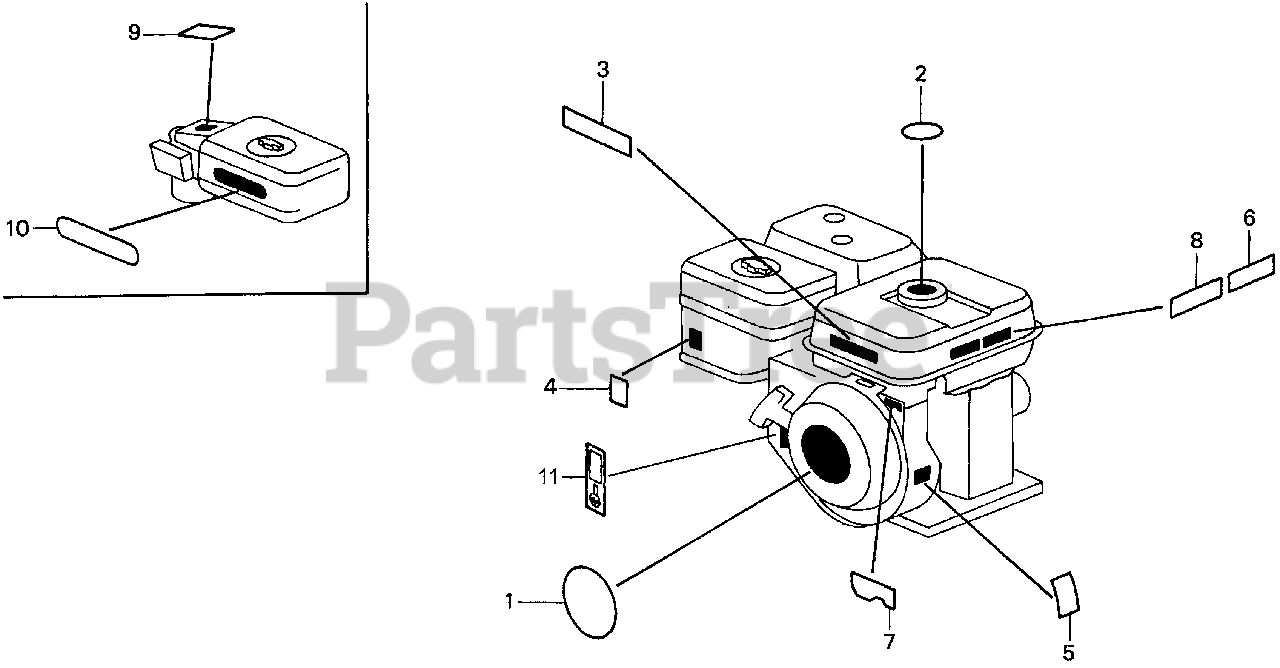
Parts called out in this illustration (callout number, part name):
1	EMBLEM (INTERNAL)
1	EMBLEM (5.5)
2	MARK, CAUTION (EXTERNAL)
3	LABEL, CAUTION
4	MARK, CHOKE
5	LABEL, SPECIFICATION (EXTERNAL)
6	MARK, OIL ALERT (GERMAN)
6	MARK, OIL ALERT (FRENCH)
7	MARK, OIL ALERT (EXTERNAL)
8	MARK, OIL ALERT (E)
11	LABEL (E-SPEC)
